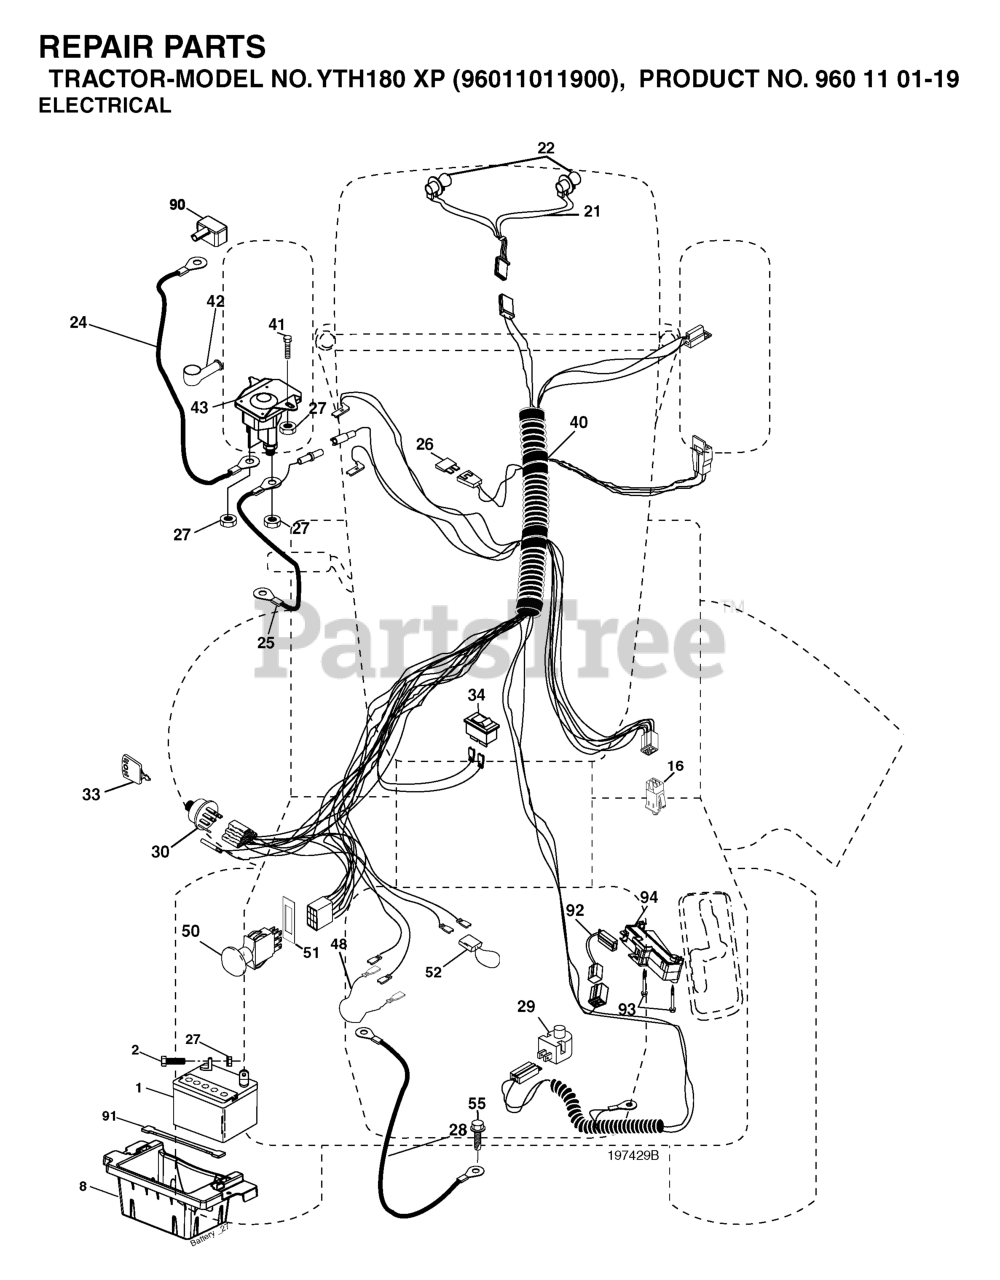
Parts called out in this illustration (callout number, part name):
1	BATTERY 12V .35 AMP
2	BOLT.HEX.1/4.X.3/4.DICHROMATE
8	BOX.BATTERY.MOUNT.FRONT.LT
16	SWITCH INTERLOOK PUSH-IN
21	HARNESS.W/LIGHT SOCKET
24	BATTERY CABLE GT
25	CABLE BATTERY 6 GA 22" W/16W
26	FUSE 20AMP
27	NUT
28	CABLE GROUND 6 GA 21" 90T BLK
29	SWITCH.SEAT.DP W/RAMPS
30	SWITCH.IGN.DELTA.W.LGH.ROS
33	KEY MLD GEN DELTA
40	HARNESS.IGN.ELEC.STL.N/RELY.05
41	BOLT
42	TERMINAL COVER
43	SOLENOID.W/BRASS.PLUNGER
48	ADAPTER.AMMETER
50	RP.PTO.SWITCH.8 TERMINAL.BLACK
51	FRAME RETAINING RING
52	WIRE PROTECTION LOOP
55	Screw 5/16-18 x 1/2 Hex, Self Tapping 5/16-18 x 1/2
90	COVER TERMINAL
91	STRAP.BATTERY.MOUNT.FRONT(2 2)
92	HARNESS.PIGTAIL.CONSLE
93	SCREW.PLASTITE
94	MODULE.REVERSE.ROS
